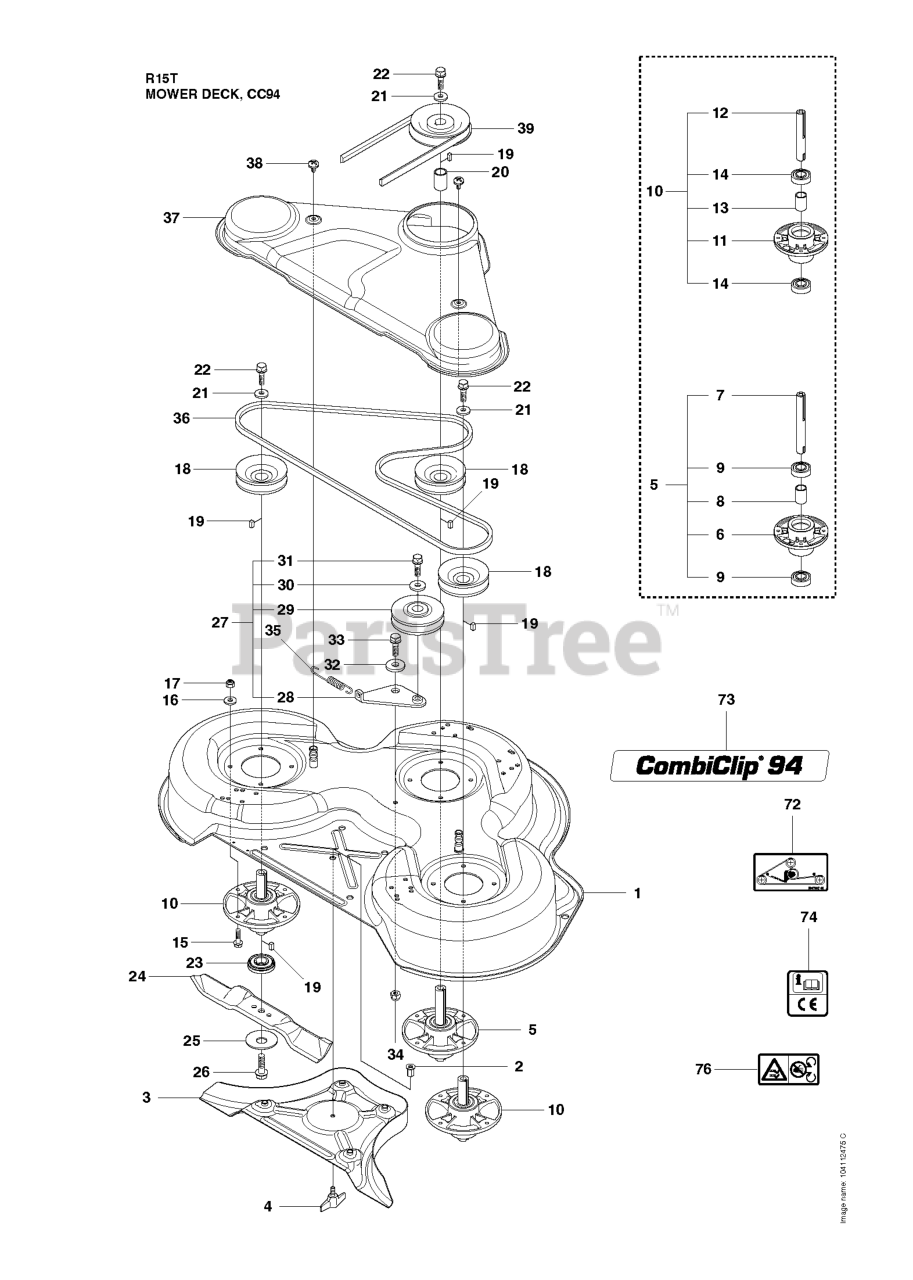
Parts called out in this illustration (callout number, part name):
1	CUTTING DECK W/PLUG GREY RIDER
3	PLUG C93 & C94
5	SPINDLE ASSY
6	BEARING HOUSING
10	RP SPINDLE ASSY
11	BEARING HOUSING
14	BALL BEARING
16	WASHER BRB 8.4X17
17	LOCKNUT M8
25	WASHER
27	BELT TENSIONER ASSY
28	BELT TENSIONING ARM
32	WASHER
34	LOCKNUT M8
37	BELT COVER C93 & C94 GREY
